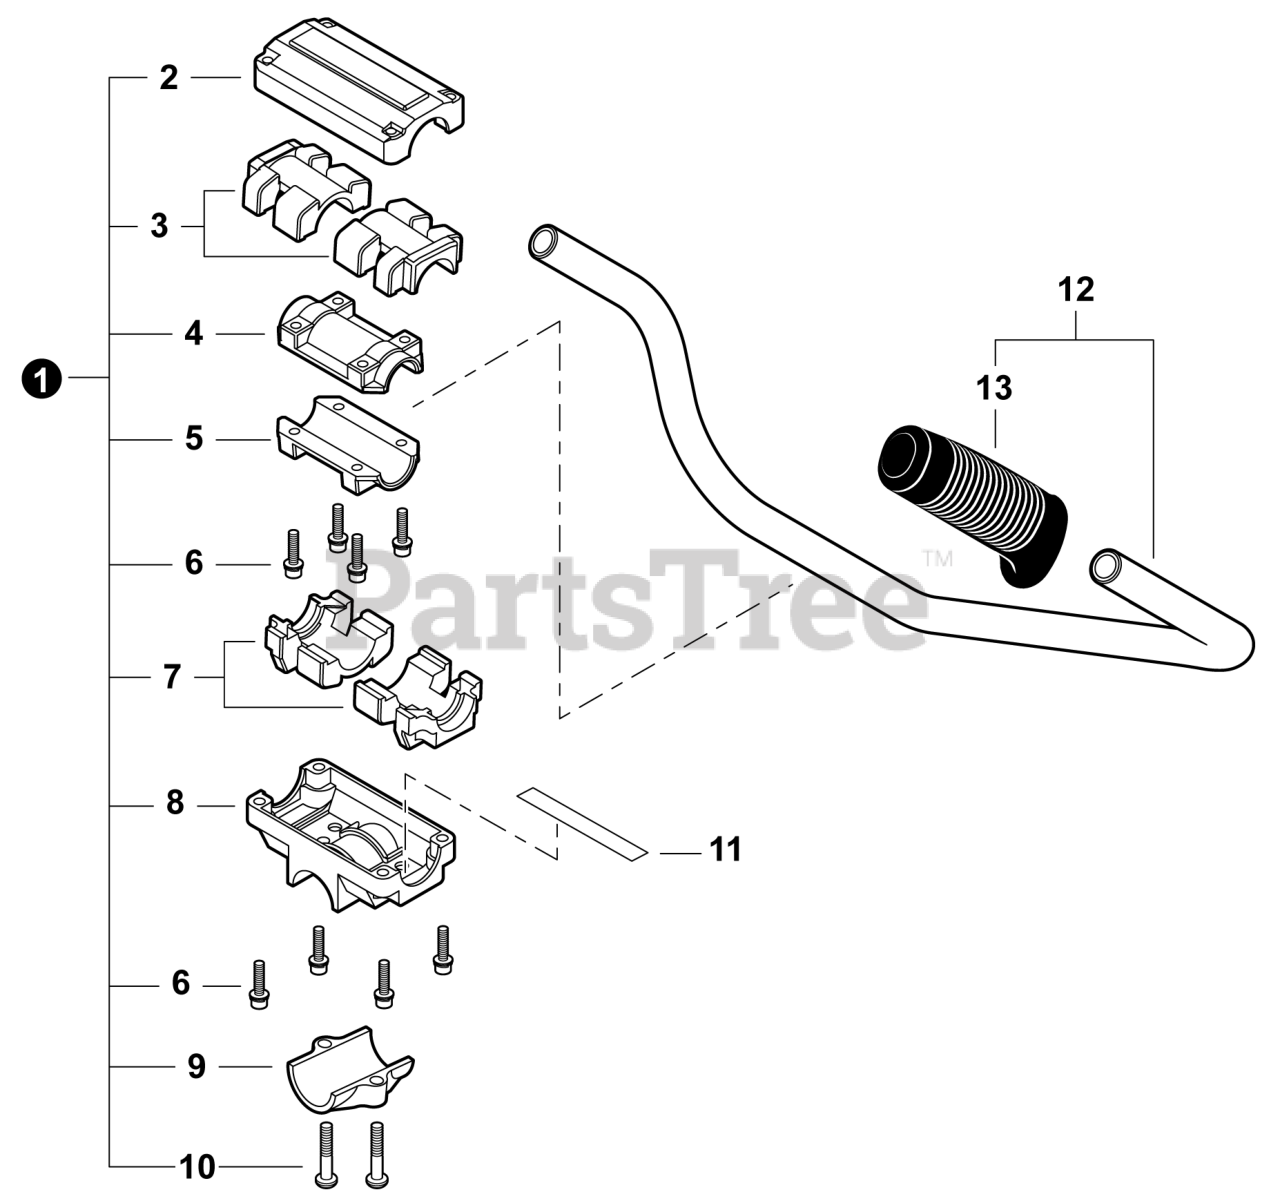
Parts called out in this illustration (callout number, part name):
1	BRACKET ASSY, HANDLEBAR
2	BRACKET, UPPER
3	CUSHION, UPPER
4	CLAMP, UPPER
5	CLAMP, LOWER
6	BOLT M5x25
7	CUSHION, LOWER
8	BRACKET, LOWER
9	BRACKET, MOUNTING
10	SCREW M6x25
11	LEAD - GROUND
12	HANDLEBAR ASSY
